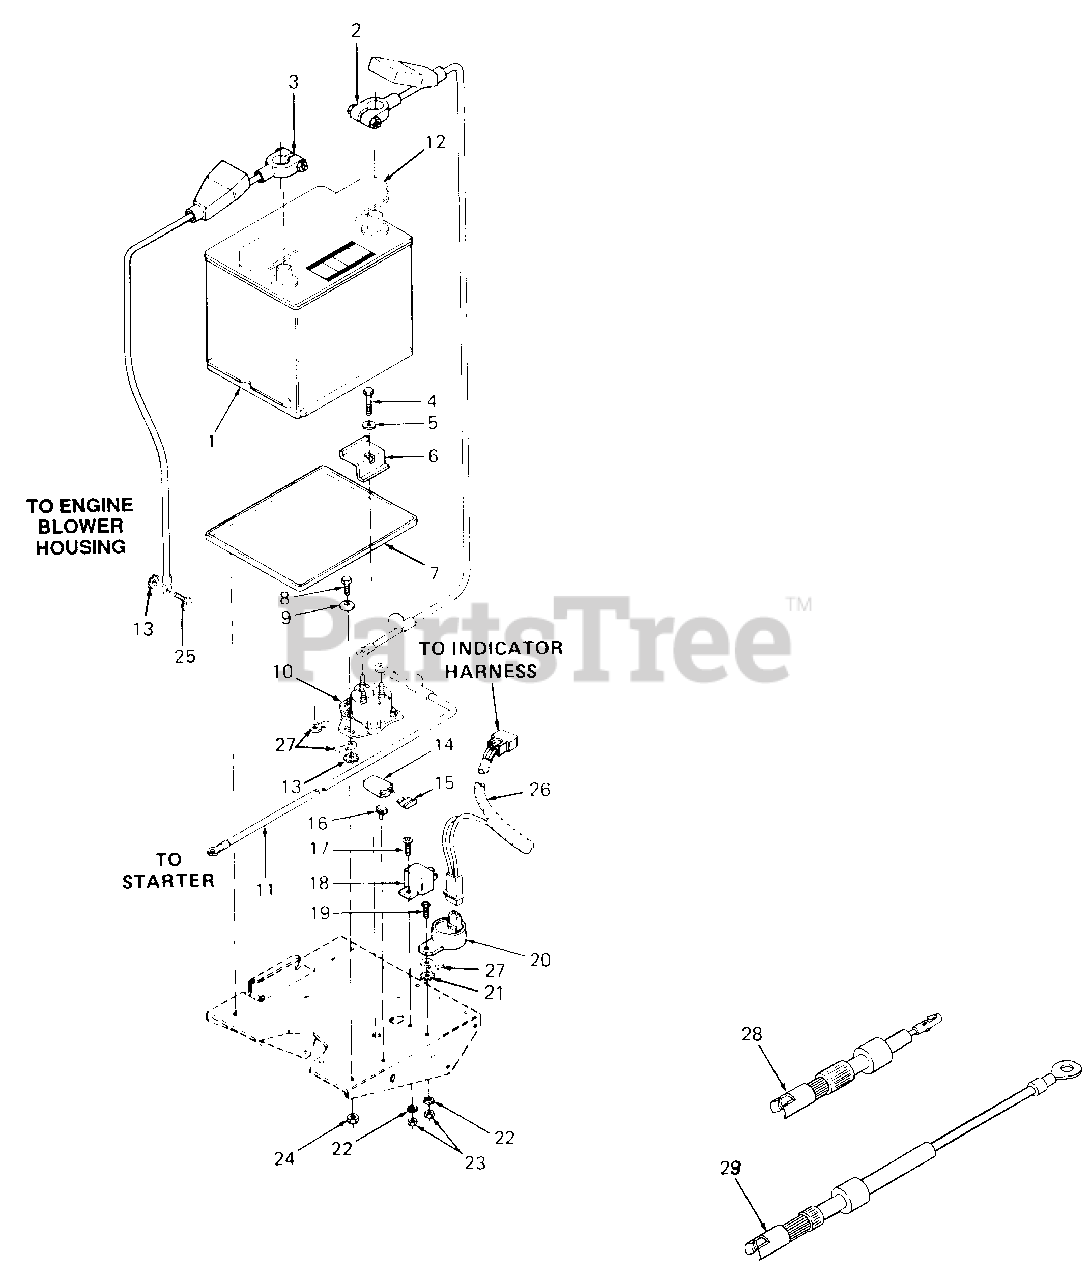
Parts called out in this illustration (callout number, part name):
1	Battery
2	Cable, Positive Battery
3	Cable, Negative Battery
4	Screw, Hex Cap, 5/16-18 X 1.38 Lg
5	Washer, Flat, .34 X .68 X .062 Thk
8	Screw, Hex Cap, 1/4-20 X .62 Lg GR5
9	Washer, Bell, .265 X .75 X .062 Thk
10	Solenoid
11	Cable, Starter
12	Cap, Battery Vent
13	Washer, Int-Ext, 1/4
14	Holder, Fuse
15	Fuse, 20 Amp
16	Clip, Fuse Holder Mtg
17	Screw, Truss Mach, #10-24 X .50 Lg
18	Relay
19	Screw, Truss Mach, #10-24 X .50 Lg
20	Indicator, Voltage
21	Washer, External, #10
22	Washer, Lock, #10
23	Nut, Hex, #10-24
24	Nut, Hex Center Lock, 1/4-20
25	Screw, Sems
26	Main Harness
27	Lug, Quick Connect
28	Diode Assy
29	Diode Assy w/Lead
